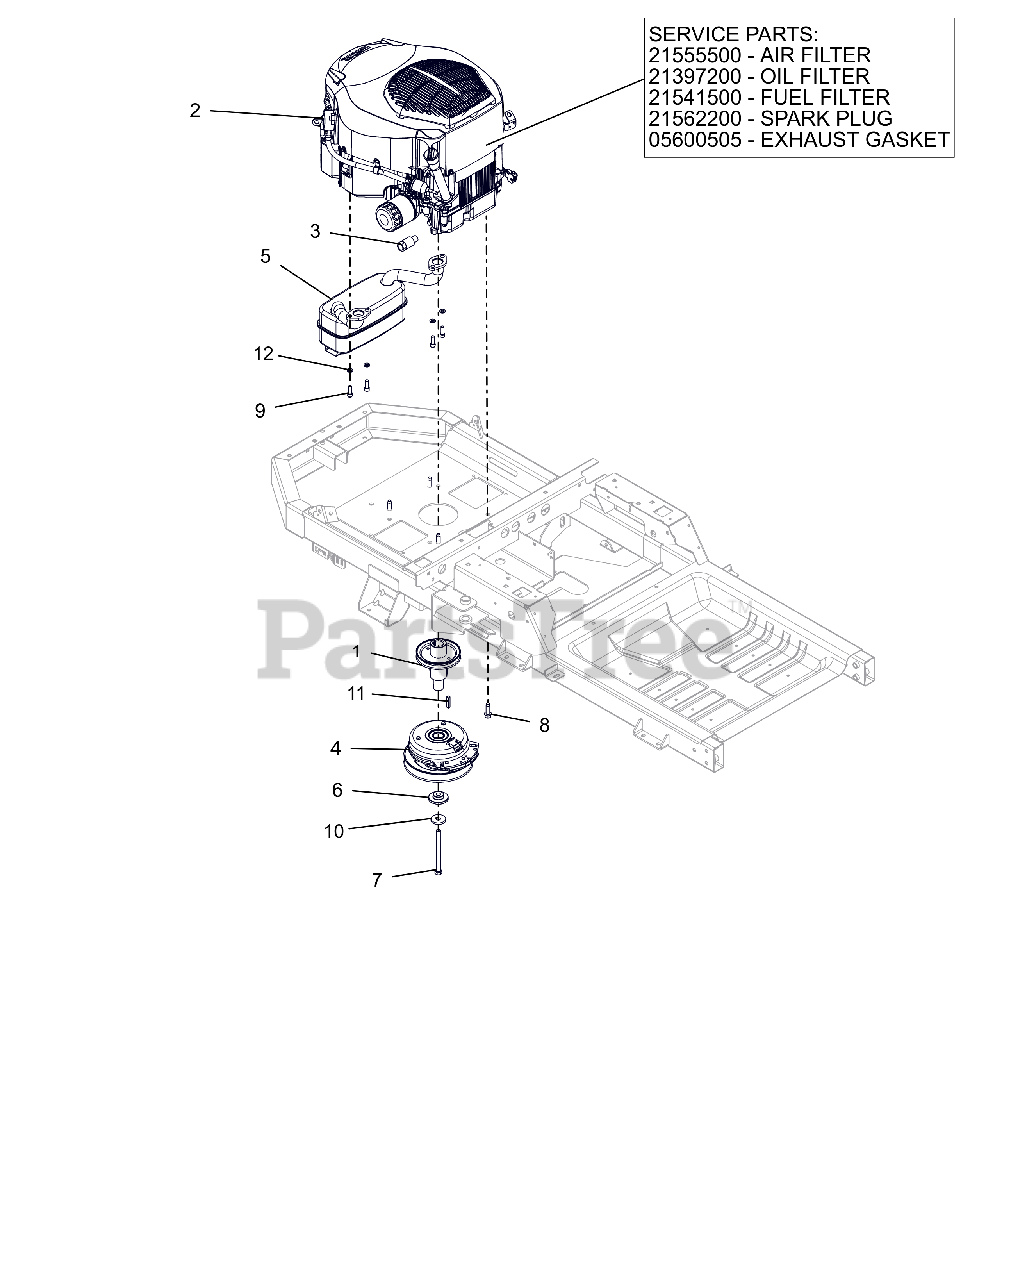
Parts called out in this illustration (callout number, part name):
1	WLDMT, DRIVE SHEAVE (LG XL)CZC
2	ENGINE, KOHLER 22HP TWIN
2	AIR CLEANER, KOHLER
2	FILTER, OIL - KOH CV20
2	FILTER, FUEL
2	PLUG, SPARK (RFI)
2	GASKET, MUFFLER COURAGE TWIN
3	DRAIN, OIL
4	CLUTCH,105FTLB MONOPOLE 6.83"
5	MUFFLER - KOHLER
6	BSHG-FLG .469X1.06X.574X2.0
7	BLT-HEX.438-20X5 GR8 YZ NYTORQ
8	SCR,TAP .375-16X1.25HWH TR ZCC
9	SCR-CAP .31-18X.88 S/HD G8 ZCC
10	WASHER, 7/16" SPRING DISK
11	KEY-SQ .25 X 1.25 X .25 SAE
12	WSHR,LK-REG .312X.078 ZCC
